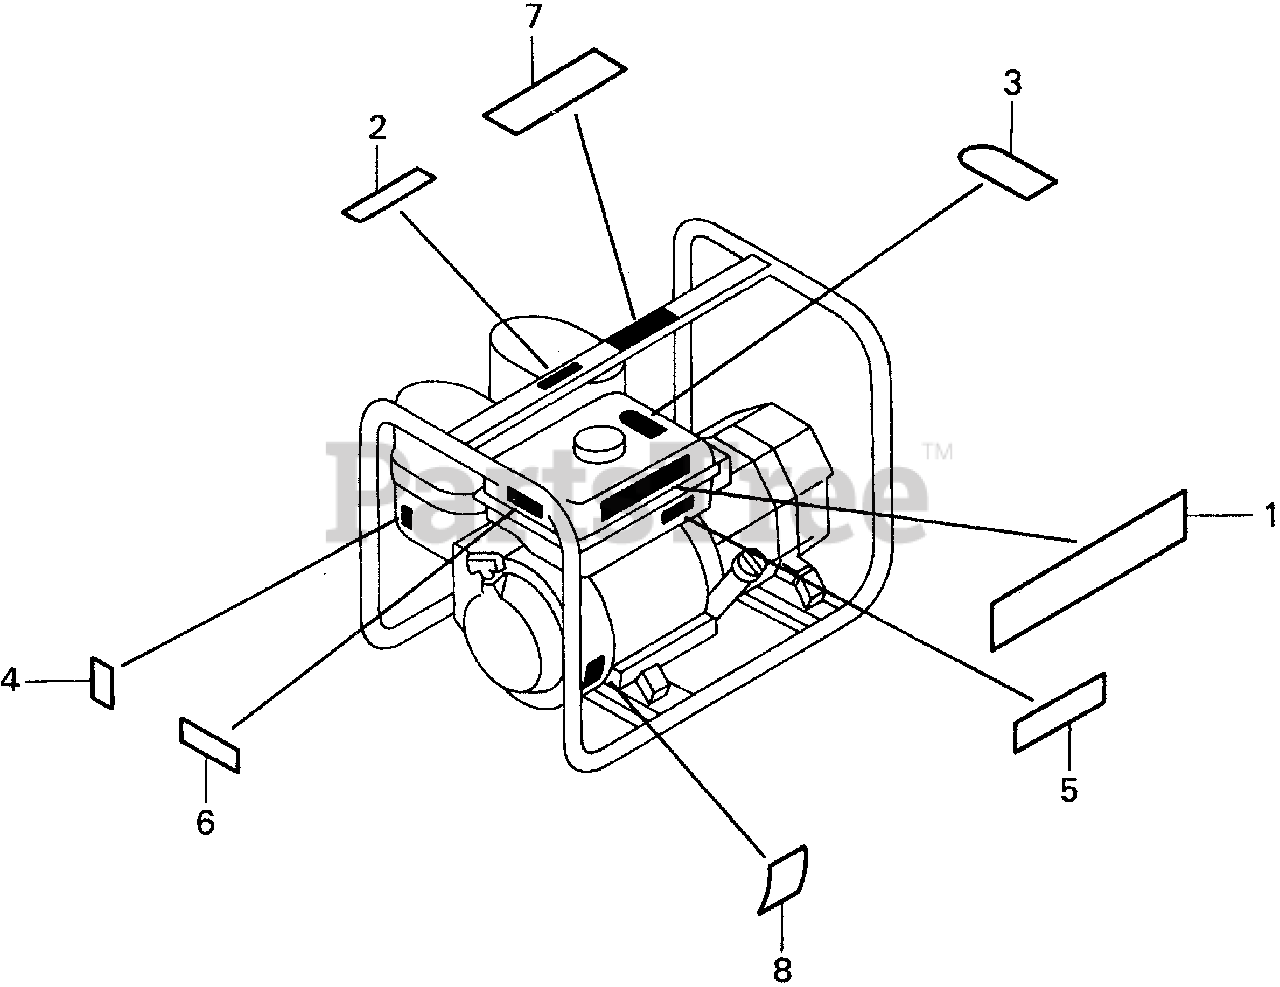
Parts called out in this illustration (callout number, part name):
1	PLATE A, CAUTION (EN5000)
2	LABEL, RAIN WARNING (ENGLISH)
3	MARK, CAUTION (ENGLISH/FRENCH)(SPANISH)
4	MARK, CHOKE (EXTERNAL)
5	MARK, OIL ALERT (E)
6	MARK, CAUTION (CO)(ENGLISH/FRENCH)(SPANISH)
7	LABEL, CONNECT WARNING (ENGLISH)
8	MARK, OIL CAUTION
